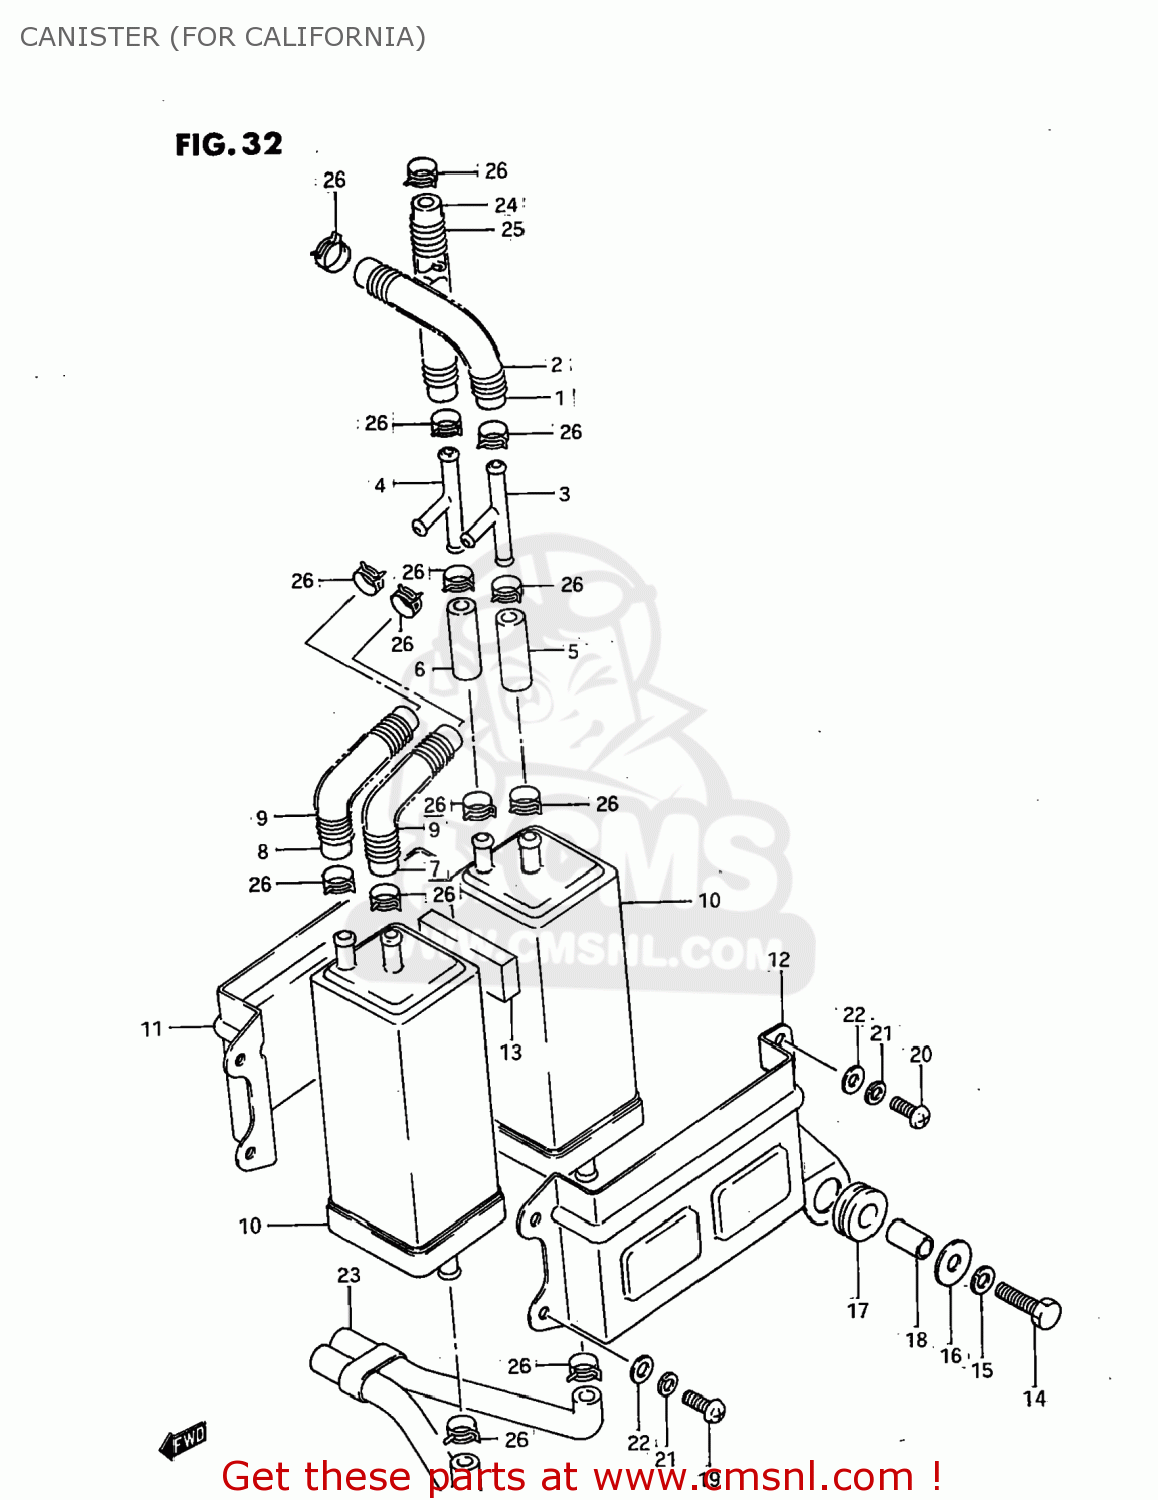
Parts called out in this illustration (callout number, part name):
1	HOSE
2	(CA) SPRING
3	PIPE
4	PIPE CANISTER
5	HOSE
6	HOSE
7	HOSE
8	HOSE
9	(CA) SPRING
10	CANISTER ASSEMBLY,CHARCOAL
11	HOLDER,CANISTER
12	(CA) PLATE,CANISTER,OUTER
13	CUSHION,CANISTER
14	BOLT
15	WASHER,LOCK
16	WASHER(6.5X18X1)
17	CUSHION
18	SPACER(6.4X9X16)
19	SCREW
20	SCREW
21	WASHER,LOCK
22	WASHER
23	HOSE,CANISTER DRAIN NO
24	HOSE
25	(CA) SPRING
26	(CA) CLIP
